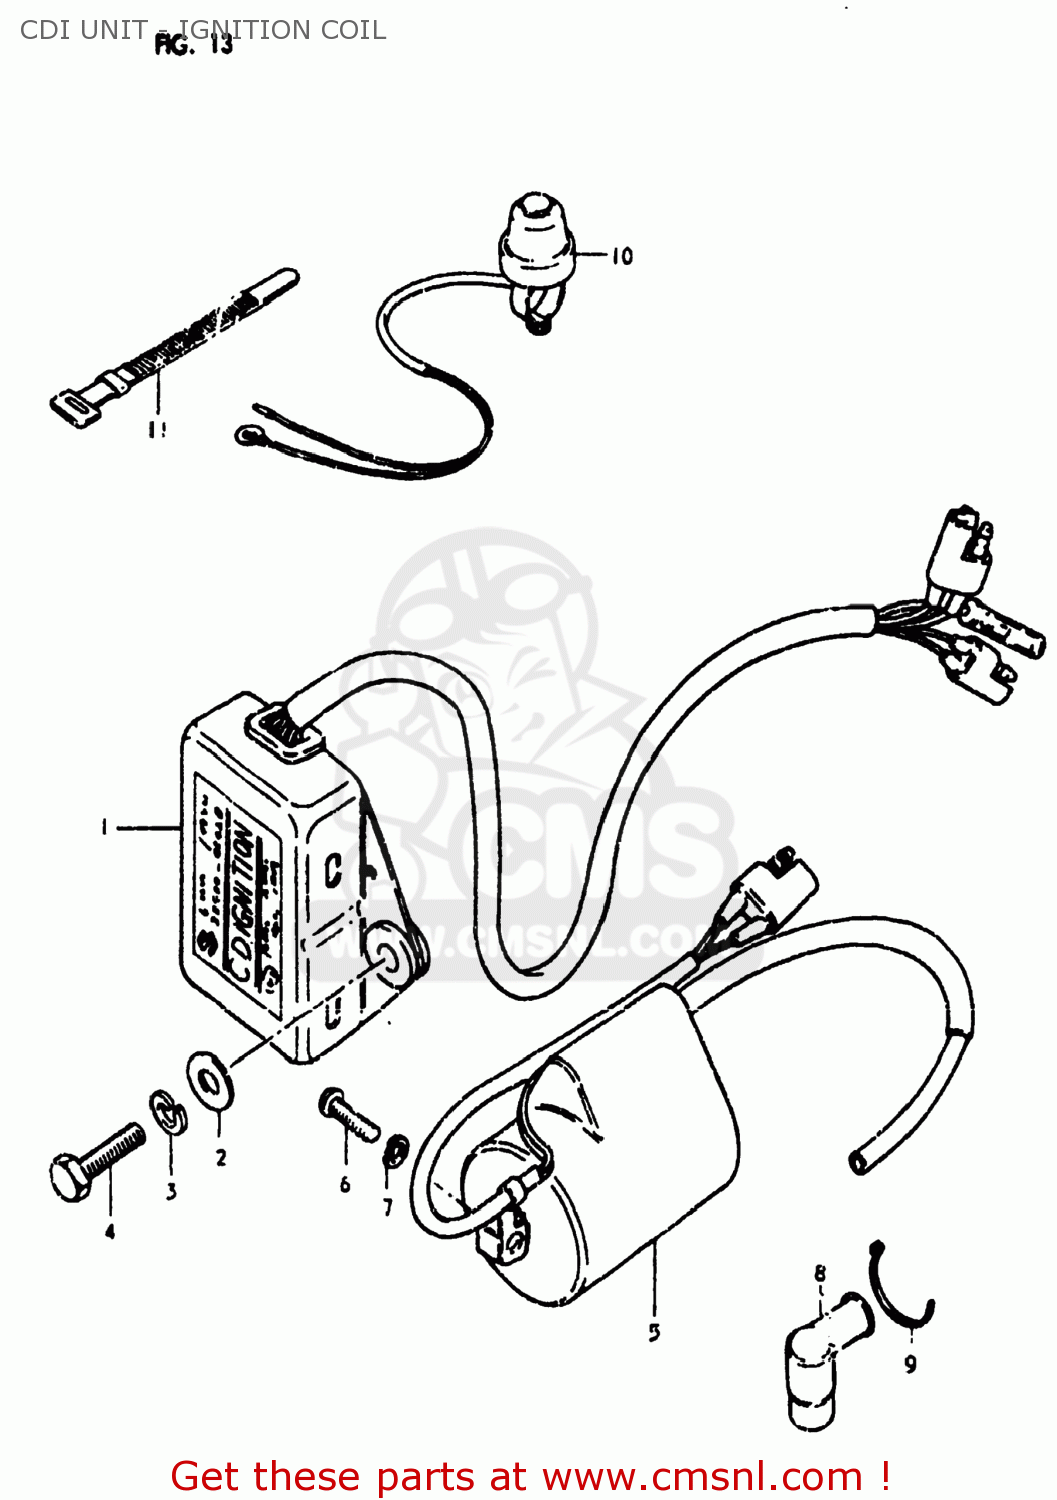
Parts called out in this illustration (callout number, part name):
1	CDI UNIT ASSEMBLY
2	WASHER(6.5X16X1.2)
3	LOCK WASHER
4	BOLT
5	COIL ASSEMBLY,IGNITION
6	SCREW 5X20
7	LOCK WASHER
8	CAP,SPARK PLUG
9	CLAMP
10	SWITCH ASSEMBLY
11	CLAMP(L:120)
